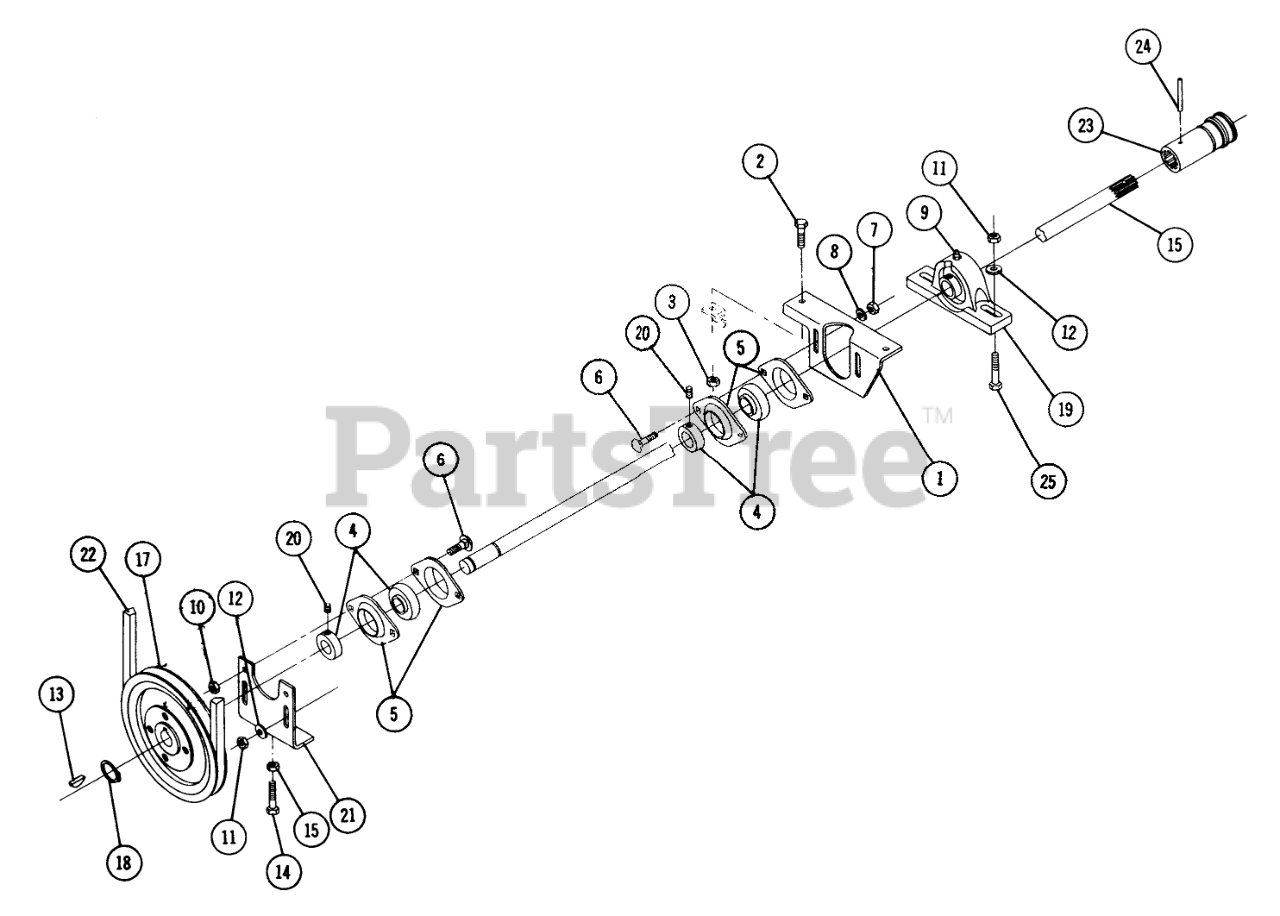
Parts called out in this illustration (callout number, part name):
1	Bracket
2	Bolt 3/8-16 x 3/4
3	Nut-Nylok
4	BEARING
5	FLANGE
6	Bolt-Car. 5/16-18 x 1
7	Nut-Nylok
8	Washer
9	ZERK 90DEGREE
10	Nut-Nylok
12	Washer
13	Key-Woodruff 1/4 x 3/4
14	Bolt Hex 3/8-16 x 1 1/2
15	3/8-16 Jam Nut
16	Shaft
17	Pulley
18	Snap Ring
19	Assembly Bearing
20	Set Screw 1/4-28 x 1/4
21	Bearing Bracket
22	BELT PTO
23	QUICK COUPLER ASSY
24	SPIROL PIN
25	Bolt-Hex 3/8-16 x 1 1/2
